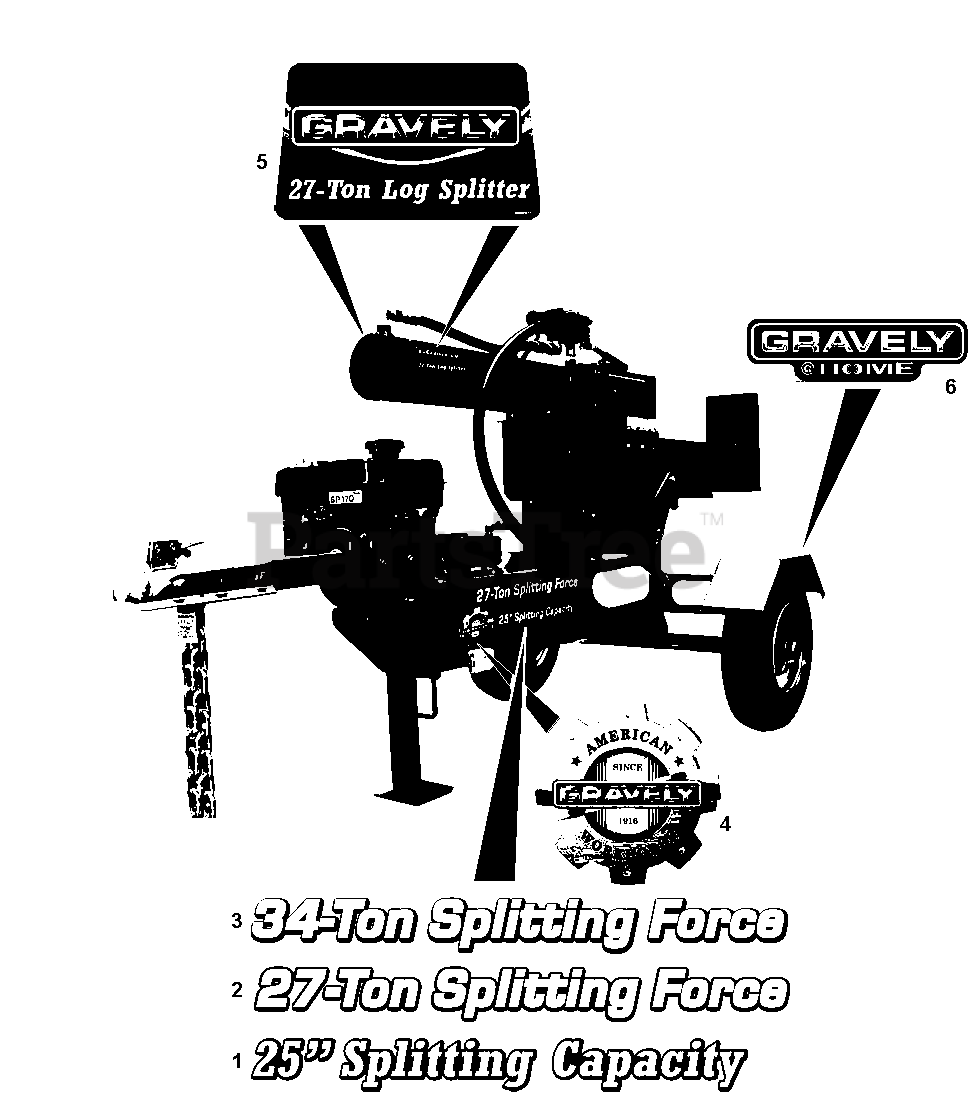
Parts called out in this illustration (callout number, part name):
1	Decal, Log Splitter 25" Length
2	Decal, Log Splitter – 27 T – Gravely (917003, 301)
3	Decal, Log Splitter – 34 T – Gravely (917004)
4	Decal, Gravely Heritage, Large
5	Decal, Splitter, Gravely 27T (917003, 301)
6	Decal, Gravely
